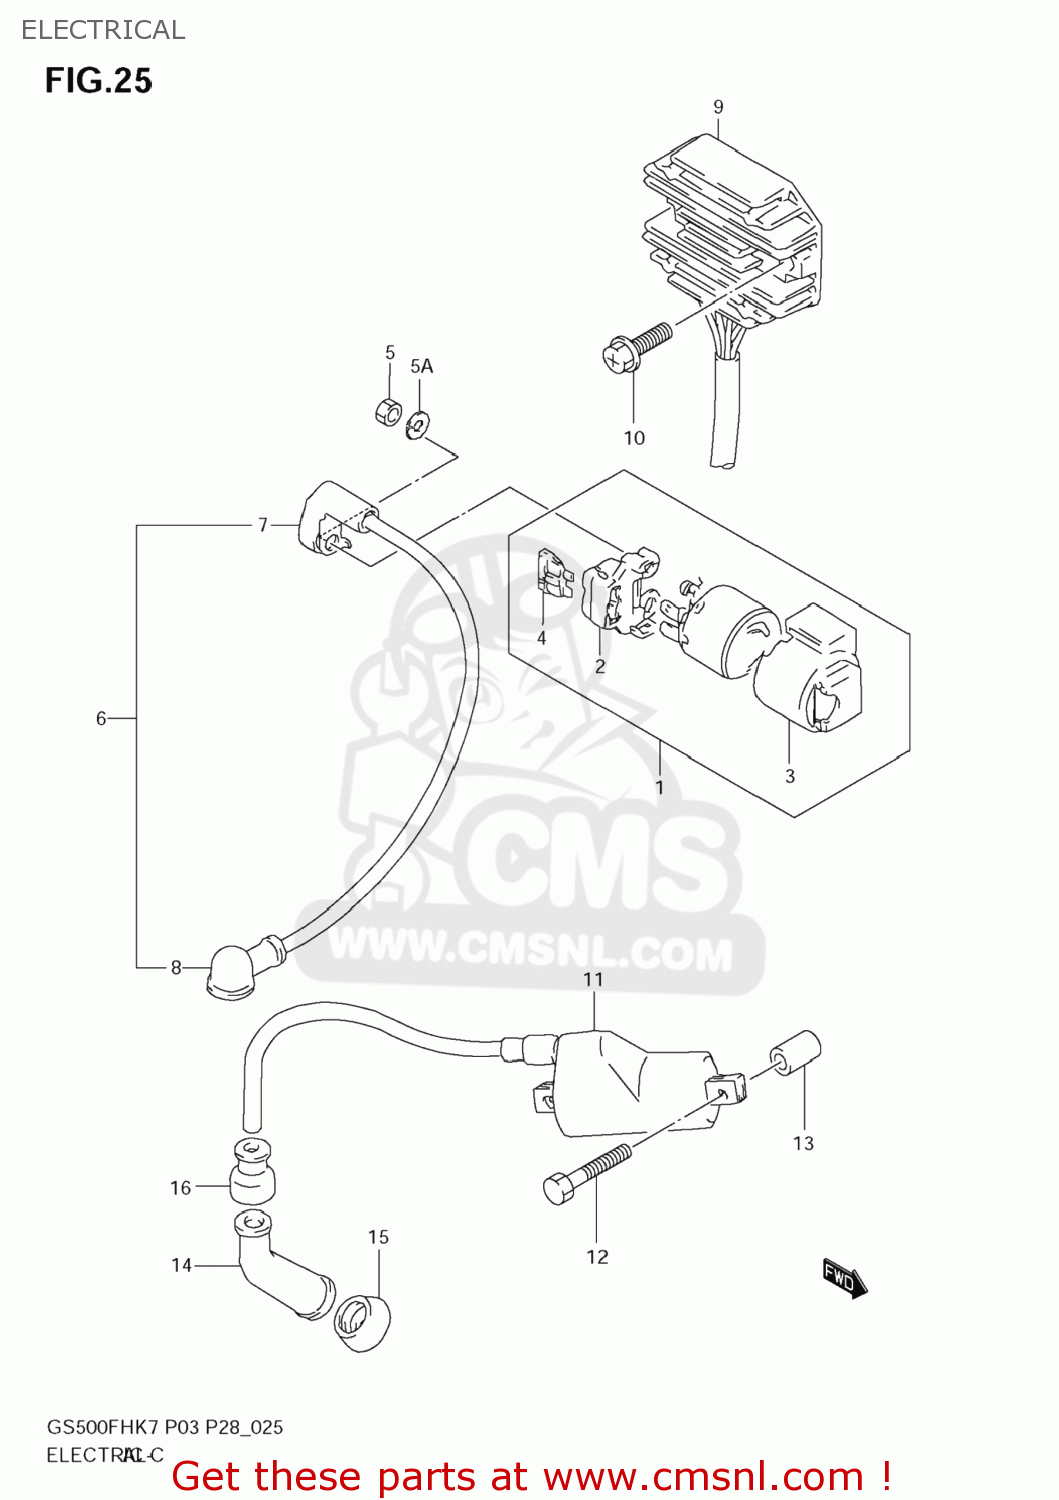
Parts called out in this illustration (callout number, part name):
1	RELAY ASSY,STARTING MOTOR
2	TERMINAL,RELAY
3	BRACKET,STARTING MOTOR RELAY
4	FUSE(20A)
5	NUT
5A	WASHER
6	WIRE,STARTER MOTOR LEAD
7	CAP,STARTER RELAY TERMINAL
8	CAP,STARTER MOTOR LEAD
9	RECTIFIER ASSY
10	SCREW
11	COIL ASSEMBLY,IGNITION
12	BOLT
13	SPACER(6.2X12X16)
14	CAP ASSY,SPARK PLUG
15	SEAL,SPARK PLUG
16	SEAL,HIGH TENSION CORD
